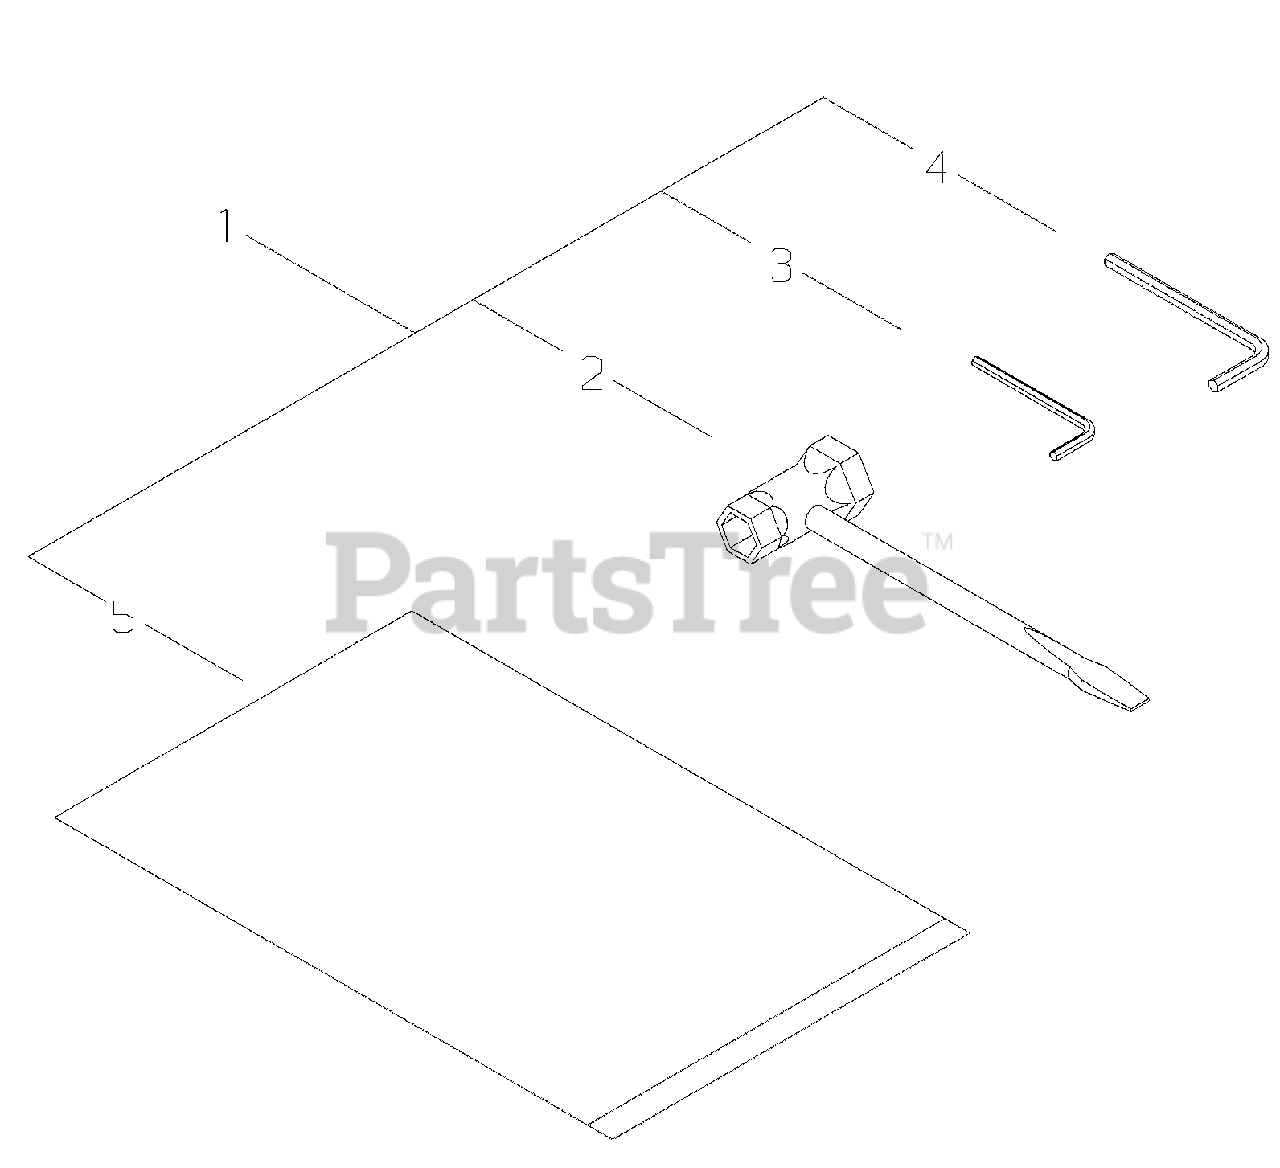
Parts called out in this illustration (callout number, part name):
1	TOOL KIT
2	T-WRENCH - 13X19mm
3	HEX KEY - 3mm
4	HEX KEY - 4mm
5	BAG, TOOL
